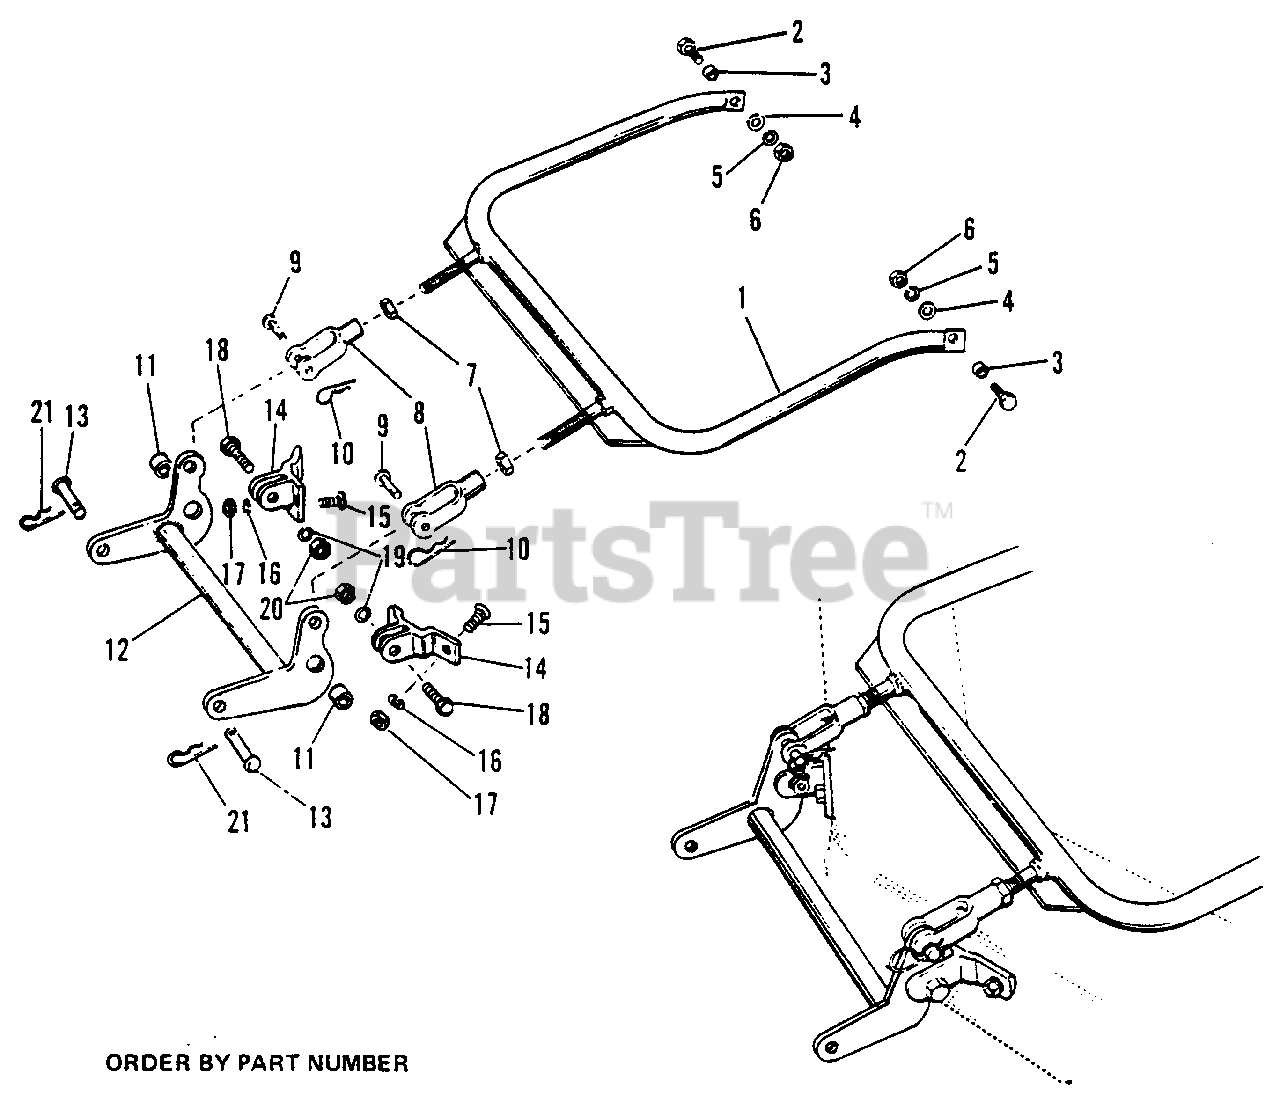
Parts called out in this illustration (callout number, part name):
1	Bail Assembly
2	Hex Capscrew, 1/2"-13 x 1-1/4"
4	Plain Washer, 7/16"
5	Lockwasher, 1/2"
6	Full Hex Nut, 1/2"-13 NC
7	Hex Jam Nut, 1/2"-20 NF
8	Yoke End, Adjusting
10	Spring Clip
12	Rocker Arm Assembly
13	Pin
14	Bracket Assembly, Front
15	Carriage Bolt, 3/8"-16 NC x 1"
16	Lockwasher, 3/8"
17	Full Hex Nut, 3/8"-16 NC
18	Hex Capscrew, 1/2"-13 x 1-1/4"
19	Lockwasher, 1/2"
20	Full Hex Nut, 1/2"-13 NC
21	Safety Clip, Pin
